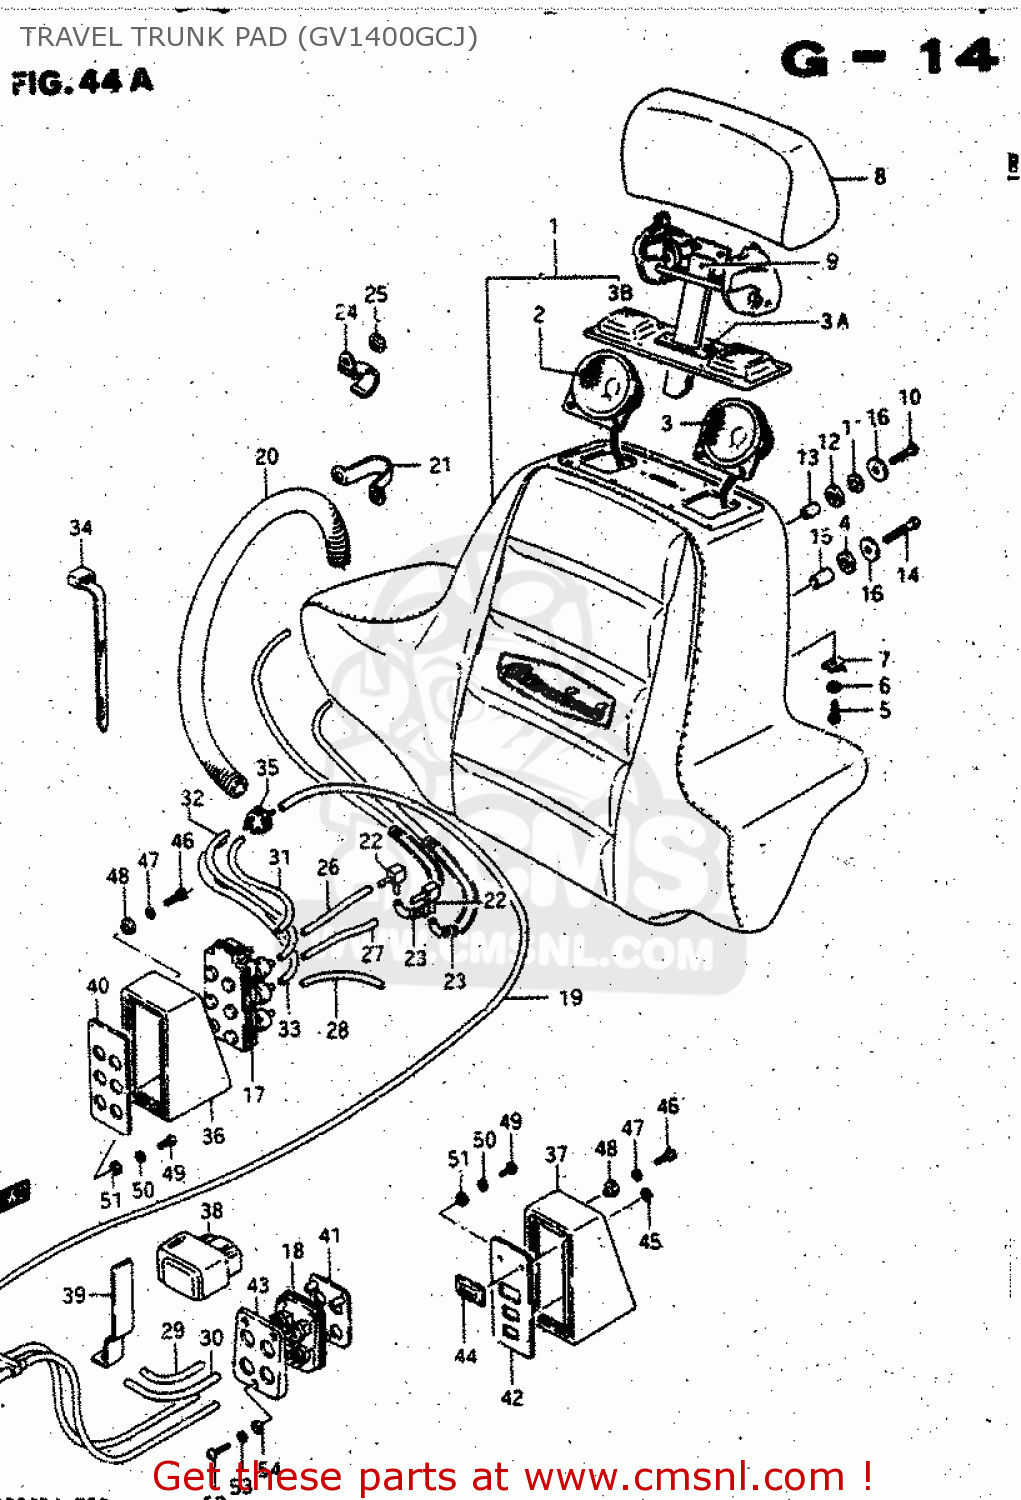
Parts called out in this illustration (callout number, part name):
1	SEAT ASSEMBLY,PILLION
2	SPEAKER
3	SPEAKER ASSEMBLY,REAR,LEFT
3A	GUIDE, ARM HEADREST
3B	COVER, REAR SPEAKER
4	CUSHION,PAD ASSEMBLY NO.2
5	SCREW
6	WASHER
7	NUT
8	PAD ASSEMBLY,HEAD REST
9	ADJUSTER,HEAD REST
10	SCREW
11	SEAL,PAD ASSEMBLY,RIGHT
12	WASHER
13	SPACER
14	SCREW (6X40)
15	SPACER
16	WASHER (6.5X22X1.6)
17	VALVE ASSEMBLY,SEAT
18	VALVE ASSEMBLY,SEAT,FRONT
19	HOSE ASSEMBLY,AIR SEAT NO
20	PROTECTOR, TRUNK HOSE
21	HOLDER, TRUNK HOSE
22	UNION
23	SPRING
24	CLAMP
25	SEAL,PAD ASSEMBLY,RIGHT
26	HOSE, OUTLET NO.1
27	HOSE, OUTLET NO.2
28	HOSE, OUTLET NO.3
29	HOSE, OUTLET NO.4
30	HOSE, OUTLET NO.5
31	HOSE, INLET NO.1
32	HOSE, INLET NO.2
33	HOSE, INLET NO.3
34	CLAMP(L:165)
35	4-WAY
36	PAD ASSEMBLY,TRAVEL TRUNK
37	PAD ASSEMBLY,TRAVEL TRUNK
38	RELAY ASSEMBLY,SEAT
39	BRACKET, SEAT RELAY
40	PANEL COMP,VALVE ASSEMBLY
41	PANEL,VALVE ASSEMBLY,FRONT
42	PANEL COMP,TUNER ASSEMBLY
43	SPACER,PANEL VALVE,FRONT
44	EMBLEM
45	NUT
46	BOLT, PAD
47	WASHER,LOCK
48	WASHER
49	SCREW
50	WASHER,LOCK 4M
51	WASHER 4MM
52	SCREW
53	WASHER,LOCK 4M
54	WASHER 4MM
55	COVER, PAD (WHITE)
56	COVER, HEADREST
